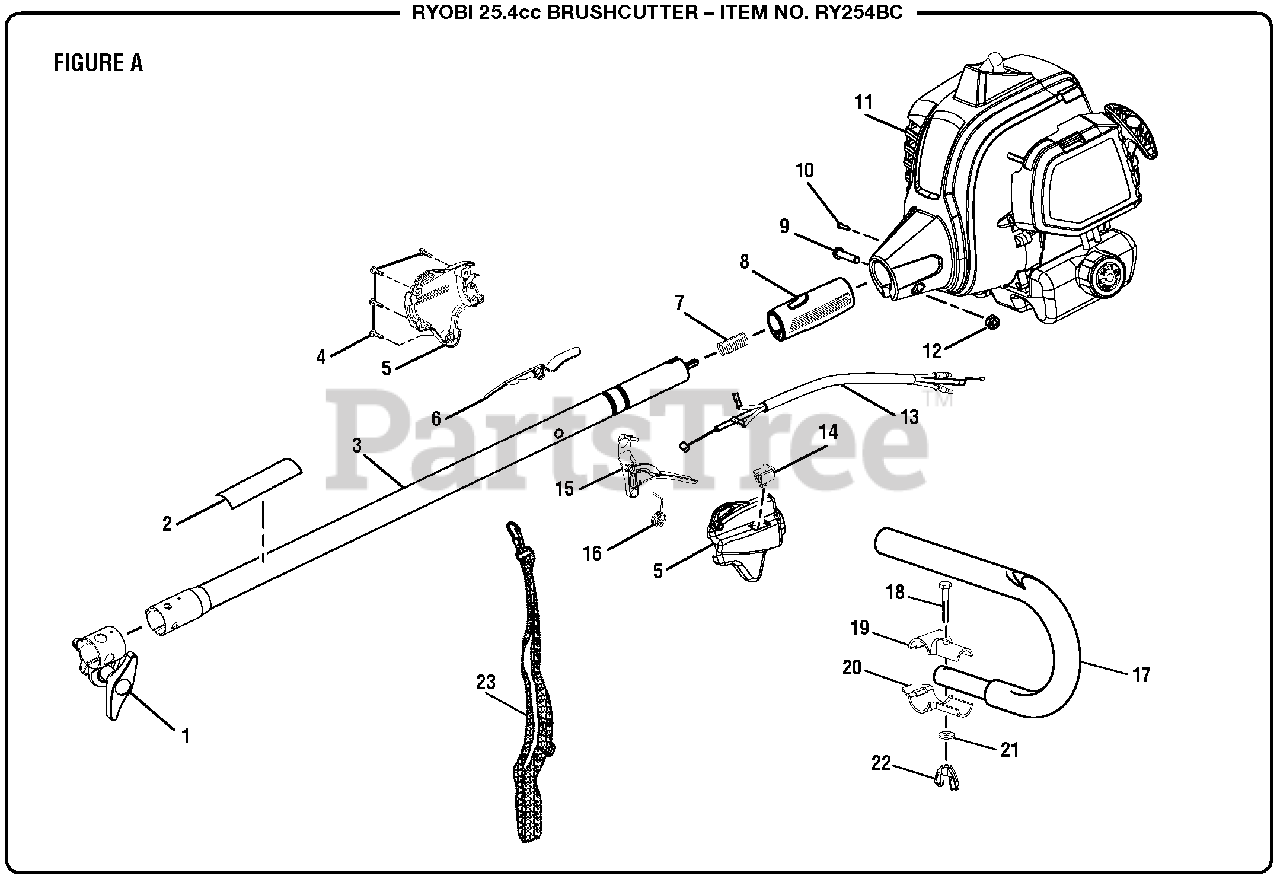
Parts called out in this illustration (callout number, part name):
1	Boom Clamp Assembly
2	Warning Icon Label
3	Upper Boom Assembly
4	Screw (M4 x 20 mm, T20 Torx Hd. S.T.)
5	Control Handle Assembly
6	Trigger Lock
7	Compression Spring
8	Rear Handle Grip
9	Screw (M6 x 30 mm, T27 Torx Button Hd.)
10	Screw (M4 x 8 mm, T20 Torx Pan Hd. S.T.)
11	Powerhead Assembly w/Labels
12	Hex Nut (M6 x 1)
13	Throttle Cable and Wire Assembly
14	On/Stop Switch
16	Trigger Spring
17	"J" Handle and Grip
18	Bolt (1/4-20 x 1-1/2 in., Hex Hd.)
19	Top "J" Handle Clamp
20	Bottom "J" Handle Clamp
21	Washer (ID7.25 x OD16 x 1.5t)
22	Wing Nut (1/4-20)
23	Shoulder Harness
